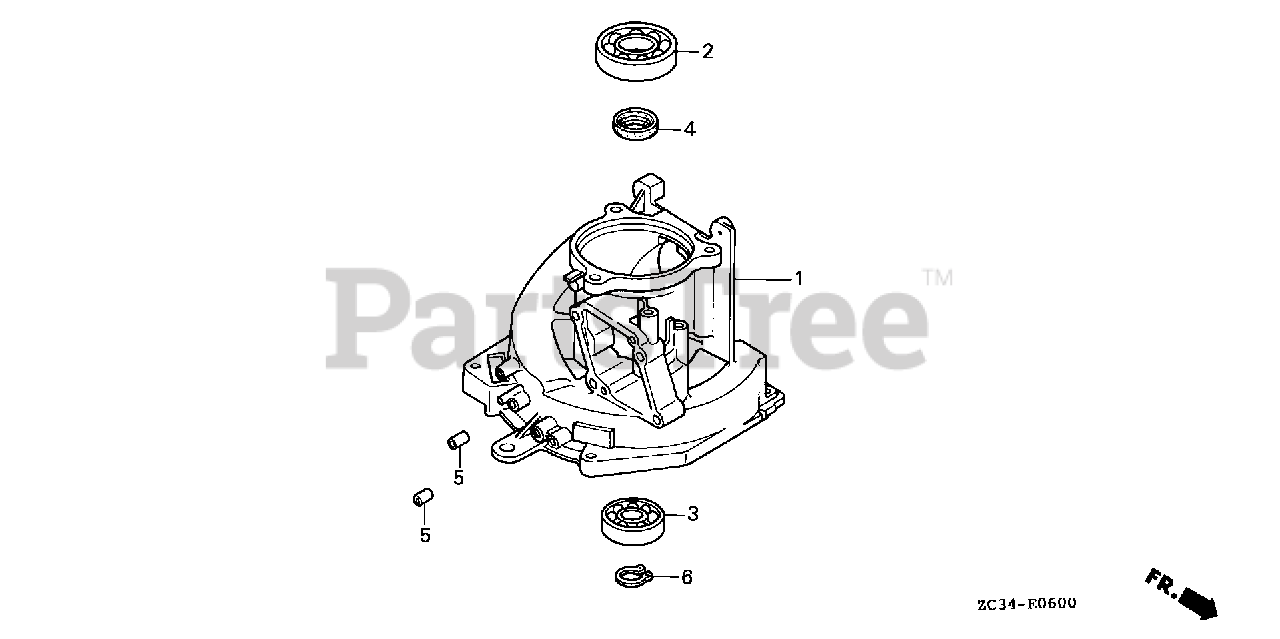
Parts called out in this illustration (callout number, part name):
1	CRANKCASE
2	BEARING, RADIAL BALL (60/22)
3	BEARING, RADIAL BALL (6002)
4	OIL SEAL (16X26X7)
5	PIN C, DOWEL (4X6.5)
6	CIRCLIP, OUTER (15MM)
